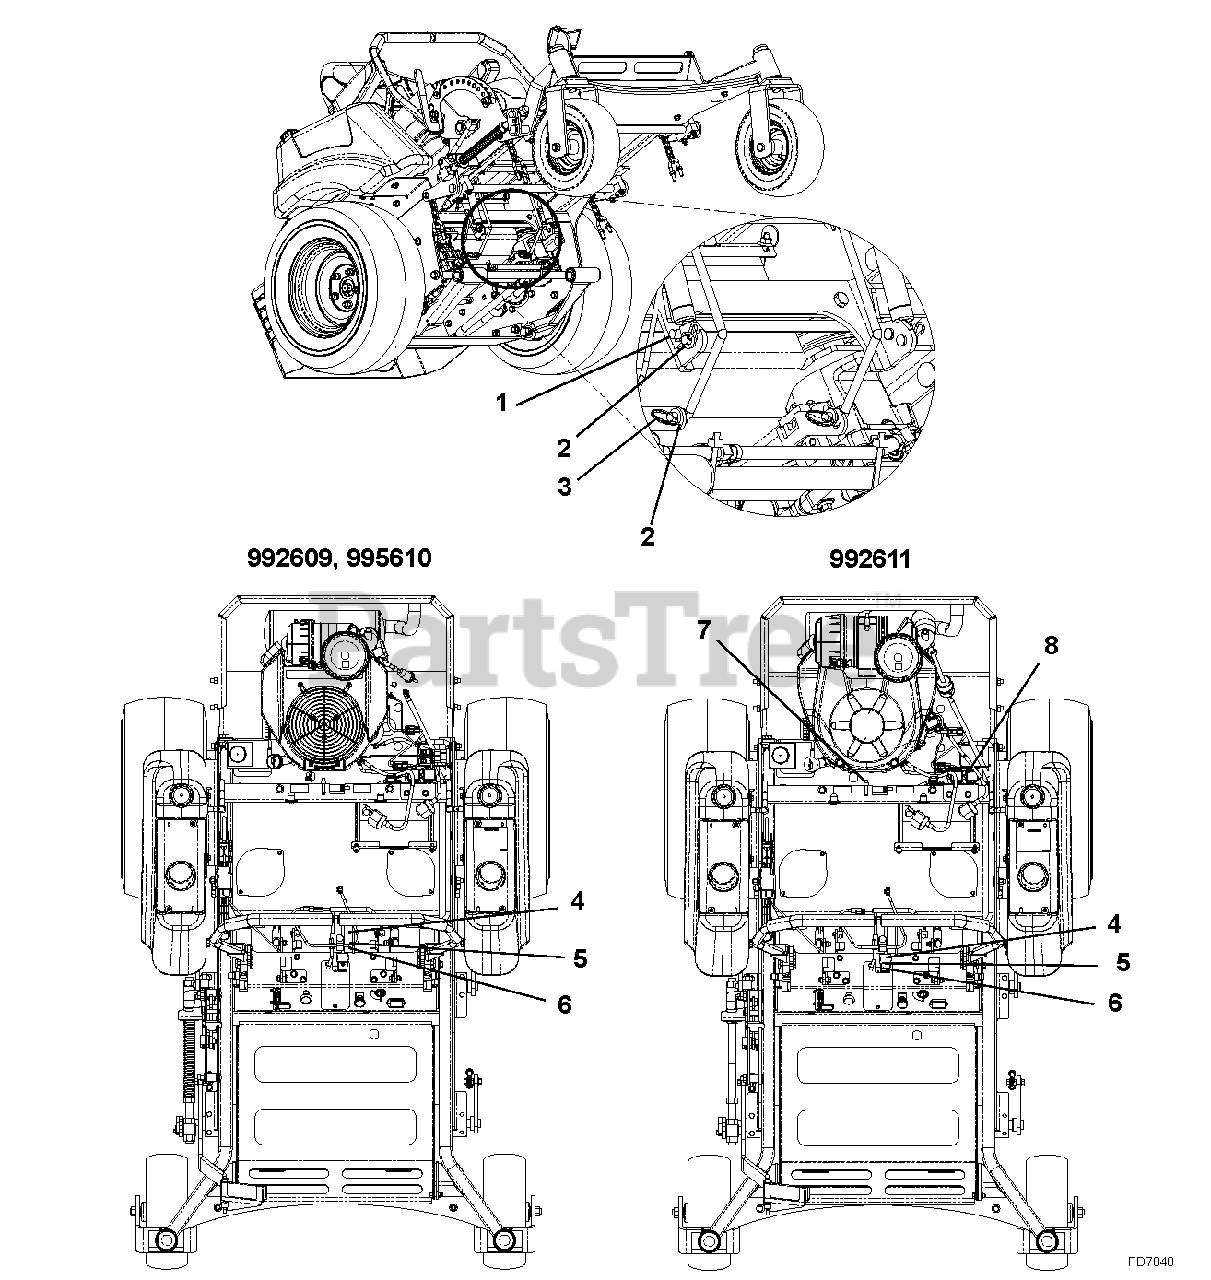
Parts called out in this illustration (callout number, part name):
1	PIN, HAR .094X1.53 5/16-1/2 Y
2	WASHER,ISO8738,10-160HV-ZN
3	RING, LOCKING
4	HARNESS. SEAT RELAY
5	SCREW, 12-24 SELF DRILLING
6	RELAY, ISO MINI ELEC.
7	CABLE TIE, .31 X 14.6 - BLACK
8	RELAY, SEALED W/BRACKET
